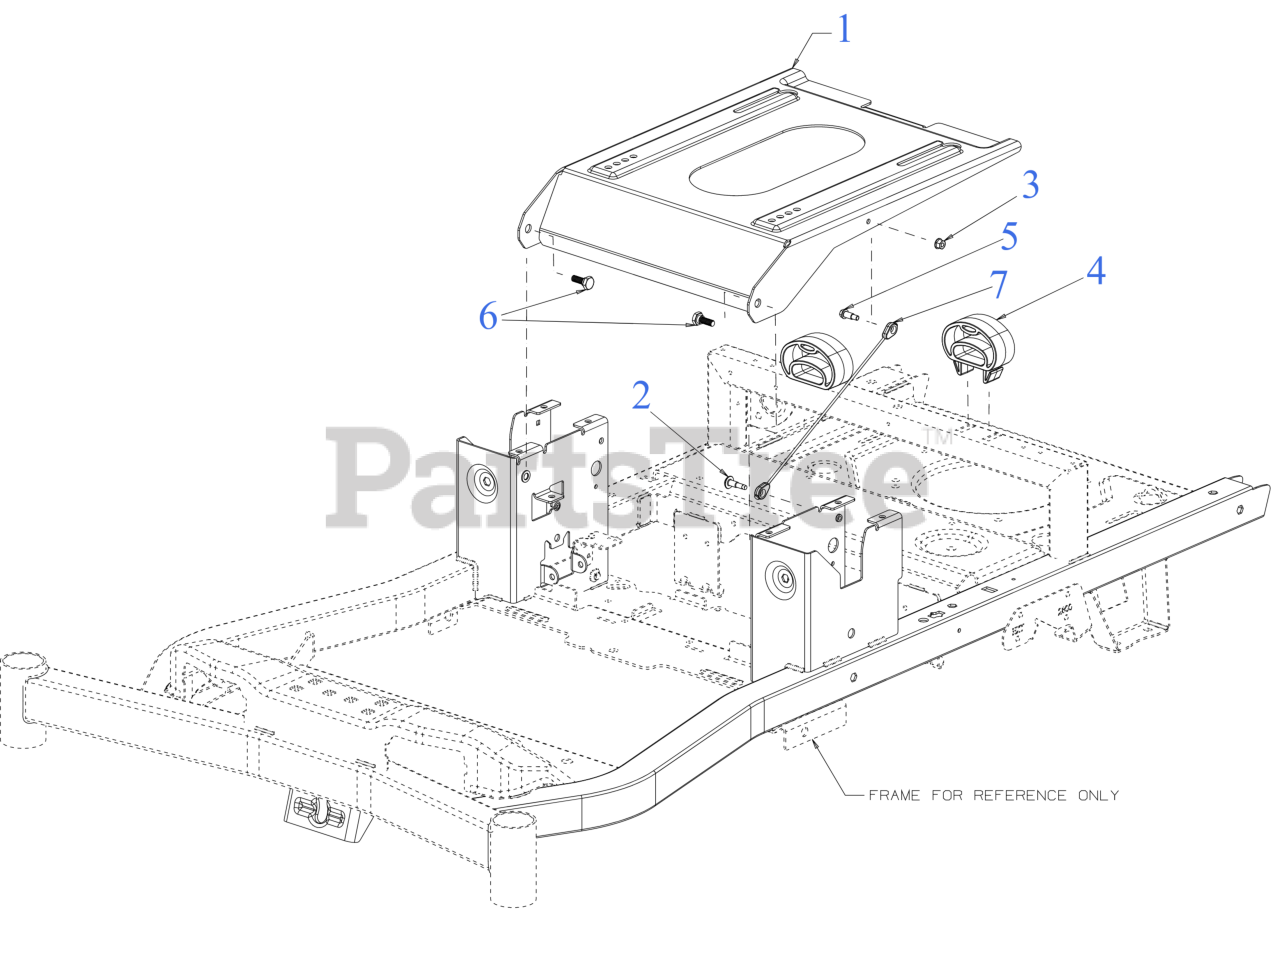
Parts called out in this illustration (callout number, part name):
1	SEAT BASE PLATE
2	BOLT 1/4-20
3	LOCK NUT 1/4
4	POLYMER SEAT SPRING
5	SHOULDER SCREW
6	SHOULDER SCREW .44DIAx.18 5/16-18
7	SEAT BASE CABLE
